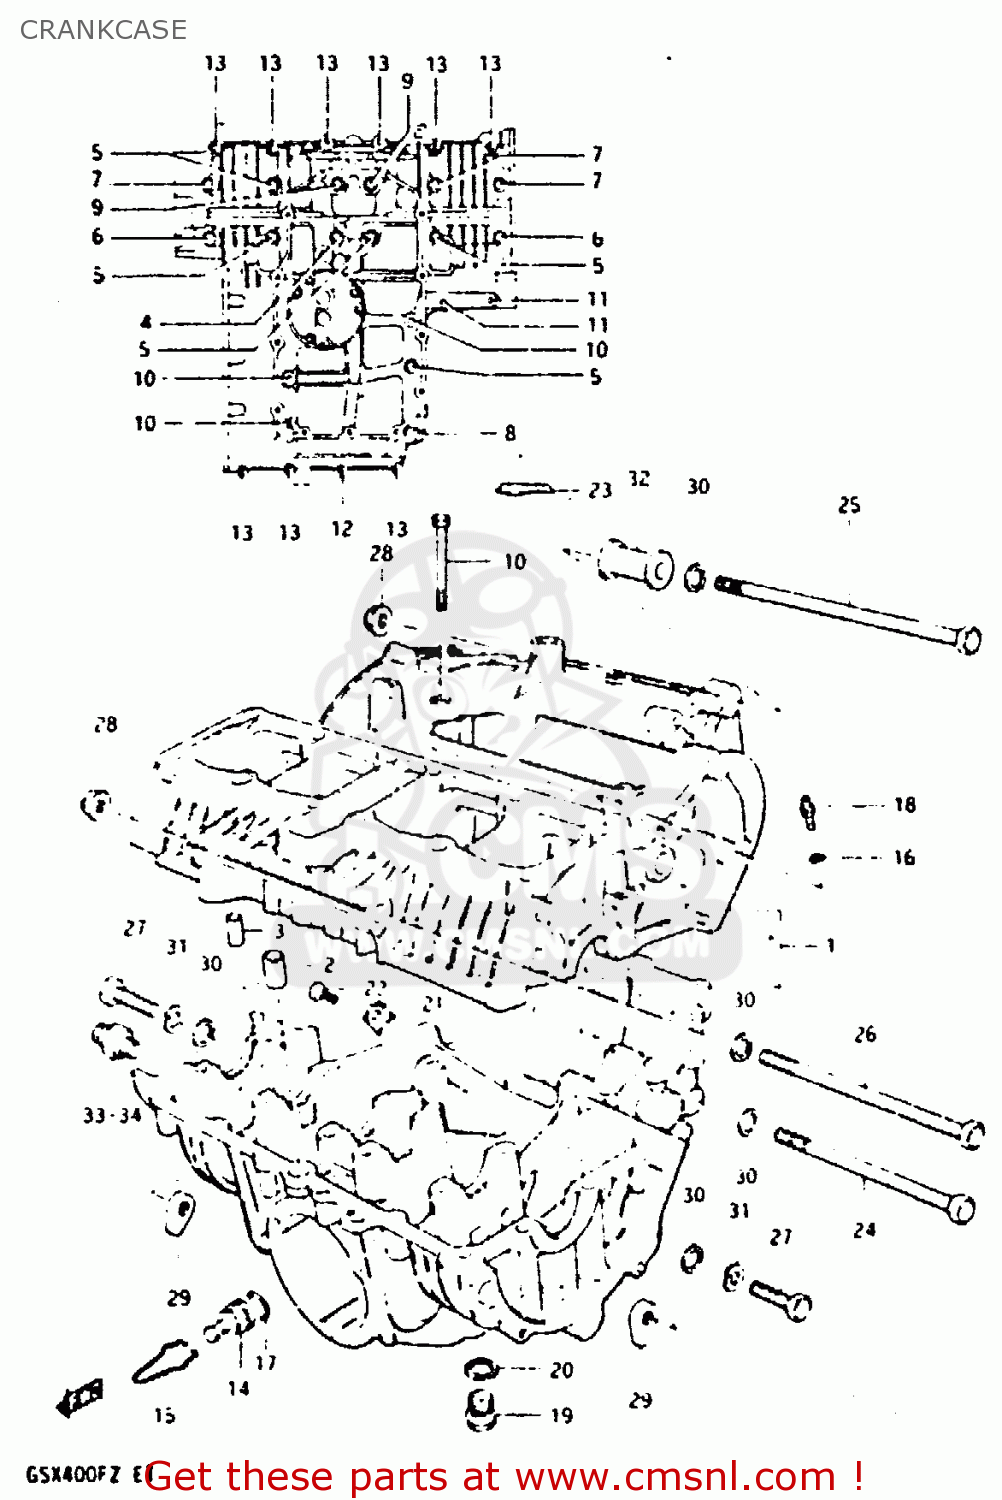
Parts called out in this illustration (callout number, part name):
1	CRANKCASE SET
2	PIN(10.4X13X22)
3	PIN (11X20)(SUS)
4	BOLT
5	BOLT
6	BOLT
7	BOLT
8	BOLT
9	BOLT
10	BOLT
11	BOLT (6X75)
12	BOLT
13	BOLT
14	JET, OIL GALLERY CYLINDER
15	CLIP
16	O-RING,OIL GALLERY JET
17	O RING(D:1.9,ID:11)
18	JET,AIR(14)
19	PLUG
20	GASKET(16X22X2) (NAS)
21	PLATE
22	BOLT
23	NOTE, ENGINE OIL
24	BOLT 10X160
25	BOLT 10X230
26	BOLT (10*180)
27	BOLT,M10X1.25X
28	NUT 10MM
29	NUT
30	WASHER
31	LOCK WASHER
32	SPACER,ENGINE MOUNT
33	SWITCH ASSEMBLY
34	SWITCH ASSEMBLY
